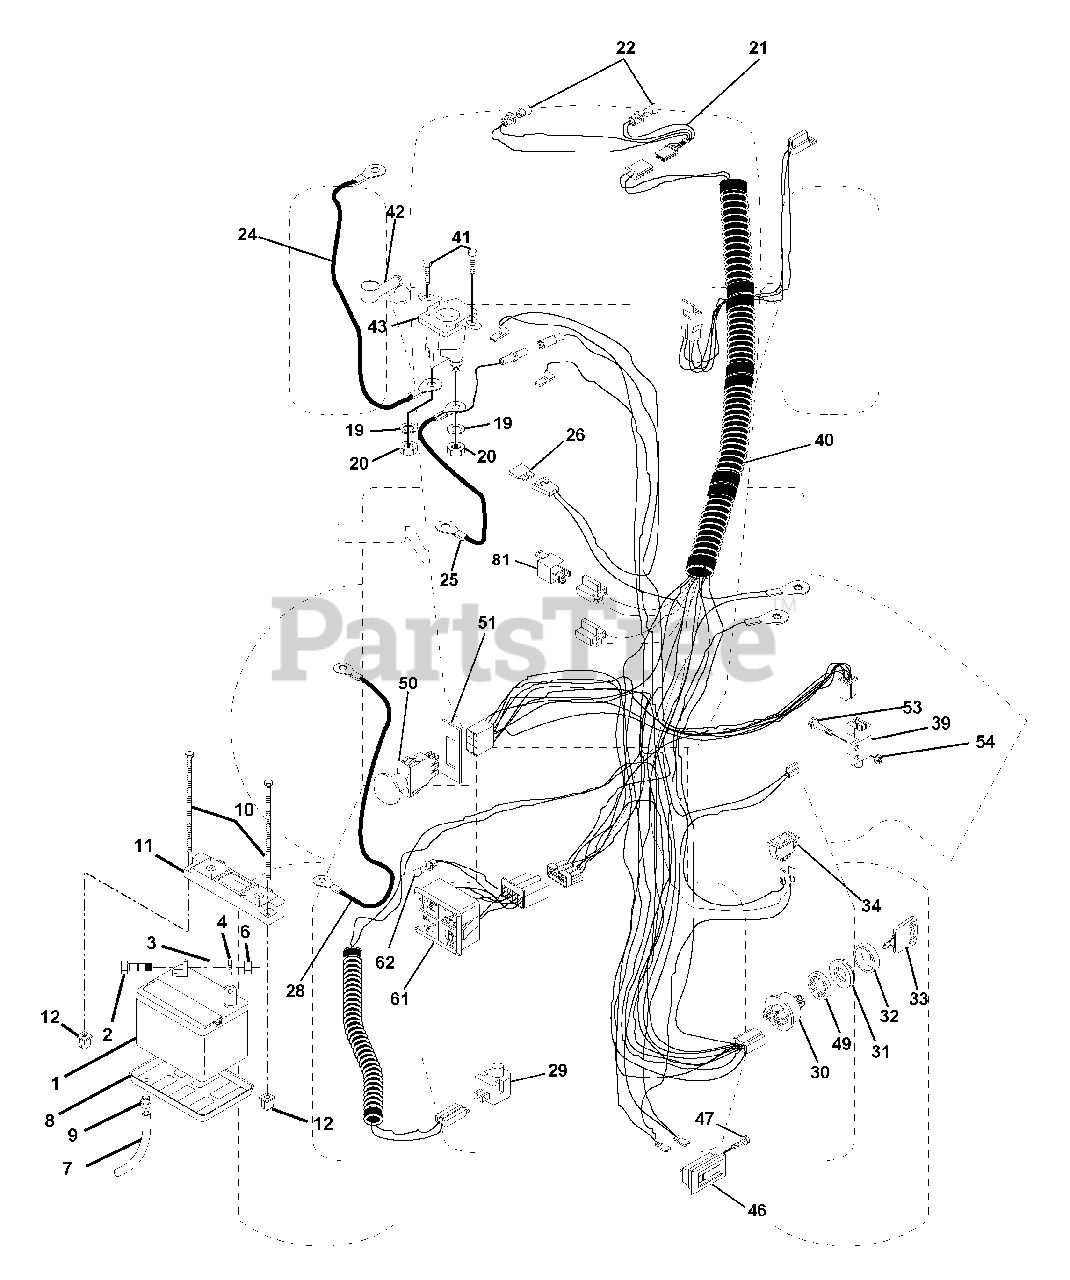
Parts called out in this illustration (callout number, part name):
1	Battery
2	Bolt Hex Head 1/4-20 x 3/4
3	Washer, Lock 1/4
4	Washer 9/32 x 5/8 x 16 Ga
6	Nut Fin Hex 1/4-20
7	Tube Plastic
8	Tray, Battery
9	Clamp, Hose
10	Bolt, Btr Frt 1/4-20 x 7-1/2 Zinc
11	Holddown Battery Dash Mount
12	Nut Push Nylon 1/4" Battery Frt.
19	Washer, Lock 1/4
20	Nut, Jam Hex 1/4-20
21	Harness Socket Light w/4152J
22	Bulb Light
24	Cable, Starter
25	Cable, Battery
28	Cable, Ground
29	Switch, Plunger
30	Switch, Ign
31	Nut, Ignition Switch
32	Cover Switch Key
34	Switch, Light
39	Intlk Switch
40	Harness Ign.
41	Screw 1/4-20 x 1/2
42	Cover, Terminal Red
43	Solenoid
46	Meter Hour
47	Screw #10-24 x 1/2
49	Washer, Pinned Delta
50	Switch, PTO
51	Ring Retainer PTO
53	Screw Hex Washer Hd #10-32 x 1
54	Nut Keps #10-32
61	Light Pkg Asm
62	Bulb, Light Pkg.
81	Relay Asm.
